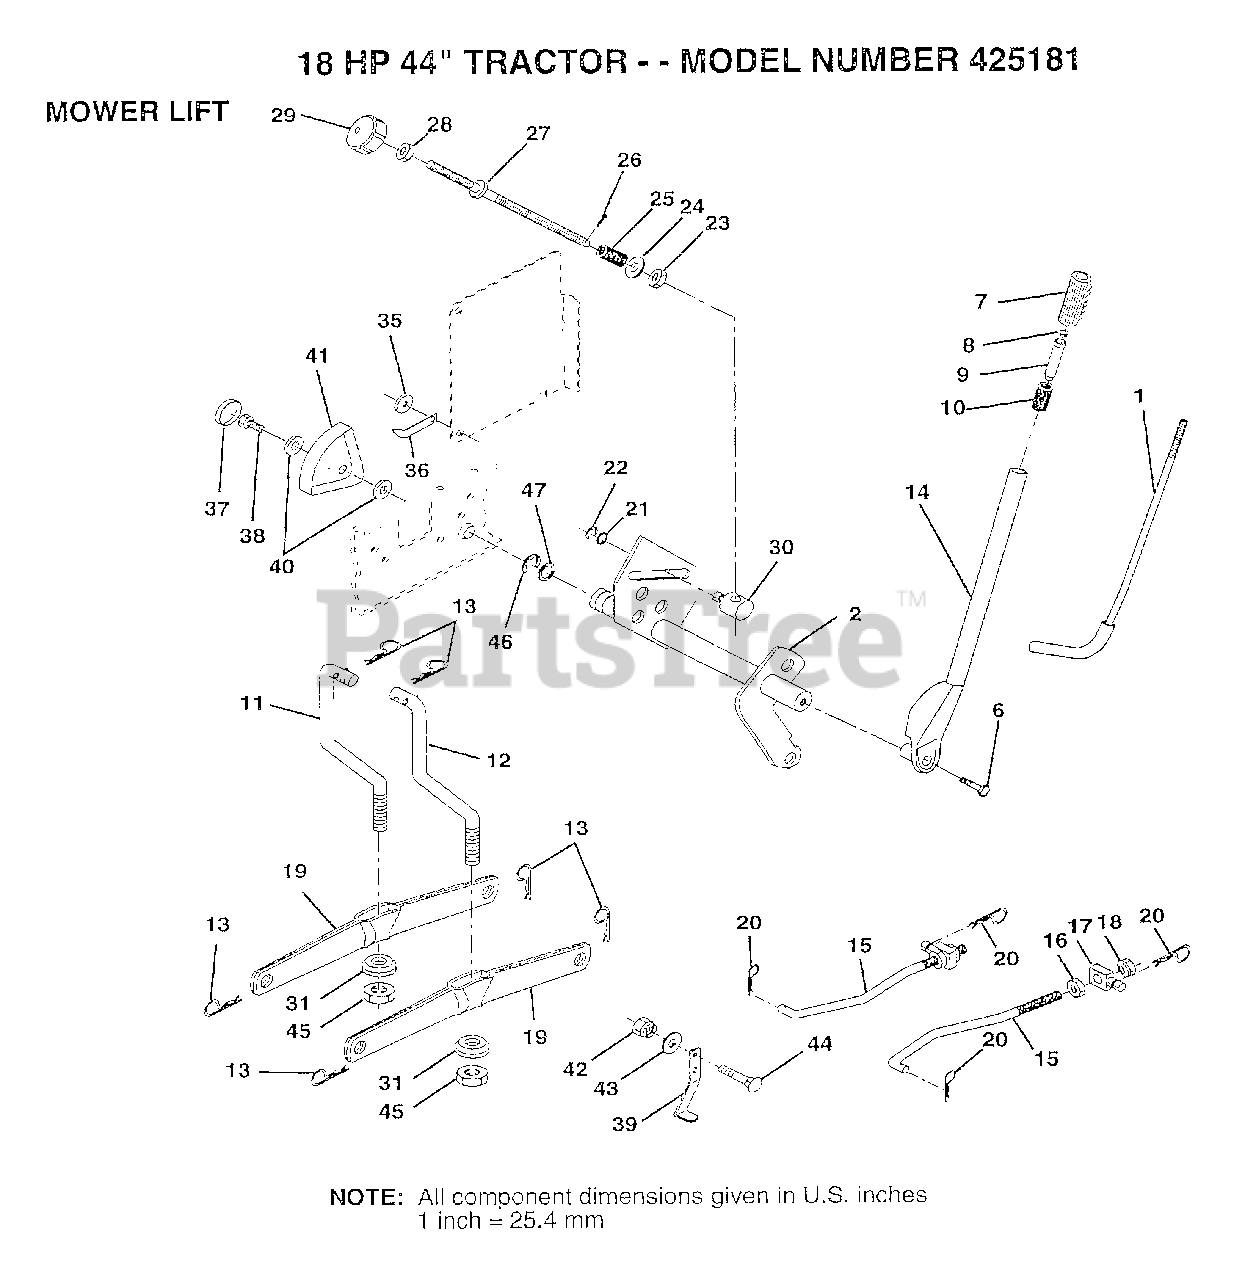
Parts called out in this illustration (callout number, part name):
1	LEVER ROD LT
2	SHAFT LIFT W/IND
4	E-RING
5	WASHER
6	"BOLT,HEX"
7	GRIP
10	SPRING T
15	LINK.FRONT
16	NUT
17	TRUNION
18	NUT.LK.W/WSH.1/2.
19	ARM SUSP REAR
20	RETAINER.SPRING
21	WASHER
22	KLIP RING
23	NUT T
24	WASHER
25	SPRING T
27	ROD LIFT LT
28	NUT
29	KNOB INF 3/8-16
30	TRUNION LT
31	BEARING PVT LH
35	WASHER T
36	POINTER HGT IND
37	"PLUG,HOLE"
38	SCREW
39	STOP.OVER.CENTER
40	WASHER
41	HEIGHT INDICATOR
43	WASHER GT
44	BOLT
45	NUT.CROWNLOCK.3/8
46	E-RING
47	WASHER
